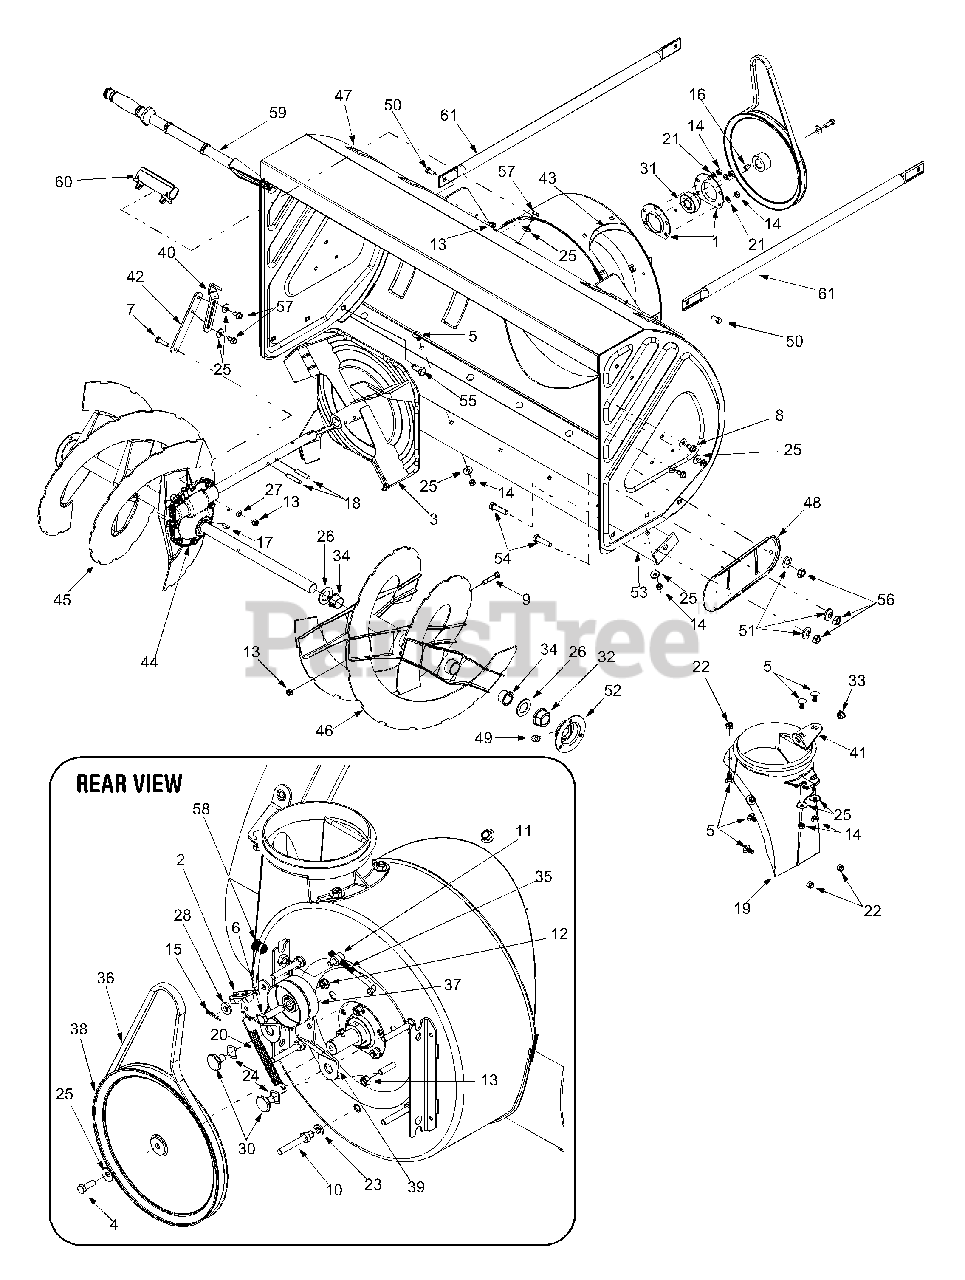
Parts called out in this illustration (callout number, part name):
1	Bearing Housing
2	Auger Brake Bracket Assembly
5	Carriage Bolt 5/16-18 x .750"
6	Hex Screw, Special 3/8-24 x 1.5"
7	Hex Screw 5/16-18 x 1.25"
8	Self-Tapp. Screw 5/16-12 x.750"
9	Shear Bolt 5/16-18 x 1.75"
11	Ferrule
12	Jam Nut 3/8-24
13	Hex Lock Nut 5/16-18
14	Hex Nut 5/16-18
15	Hairpin Clip
18	Spiral Pin
19	Chute Adapter
20	Extension Spring
21	Lock Washer
22	Flange Lock Nut 5/16-18
23	Lock Washer
24	Wave Washer
25	Beleville Washer
26	Flat Washer
27	Spring Washer
28	Flat Washer
30	Shoulder Screw
31	Self-Aligning Bearing
32	Flange Bearing w/ Flats
33	Plastic Bushing
34	Flange Bushing
35	Auger Idler Rod
36	V-Belt
37	Flat Idler
49	Lube Fitting
50	Screw, 5/16-18 x.75"
51	Bell Washer
54	Carriage Screw
55	Carriage Bolt
56	Hex Nut 3/8-16
57	Screw, 5/16-18 x.75
58	Insert Nut, 3/8-16
59	Chute Clean-out Tool
60	Chute Clean-out Tool Mount
61	Support Tube
